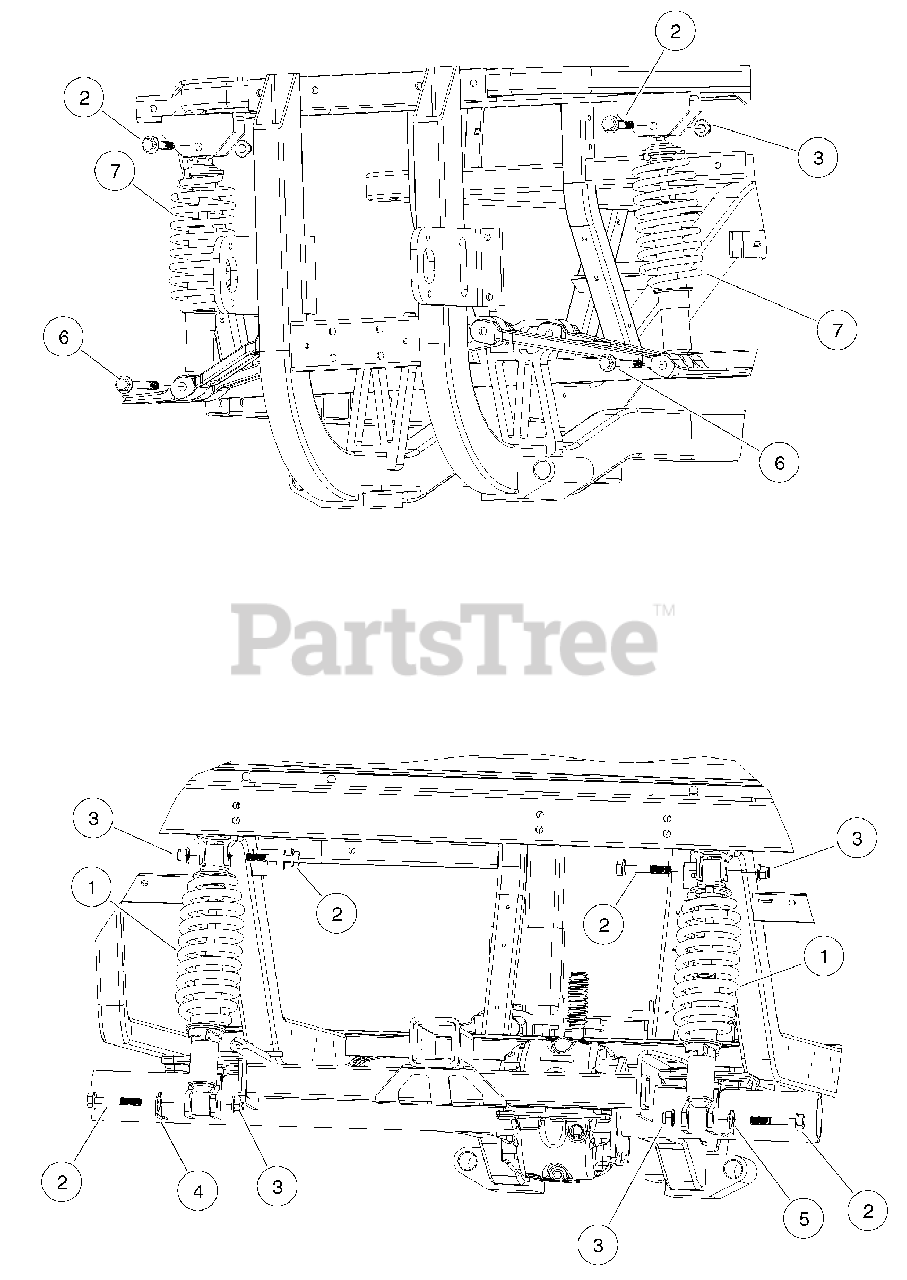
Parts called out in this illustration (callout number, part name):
1	Shock, Coil Over Rear
2	Bolt, Flange Head, M12 X 1.75 X 70
3	Nut Flg, M12x1.75, Nylon Gr 10
4	Brkt, Line, Hyd, Shk Mnt, Drv
5	Brkt, Line, Hyd, Shk Mnt, Pass
5	Bolt Flg, M12x1.75x100, Patch
7	Asm, Coil & Shock, Frt
